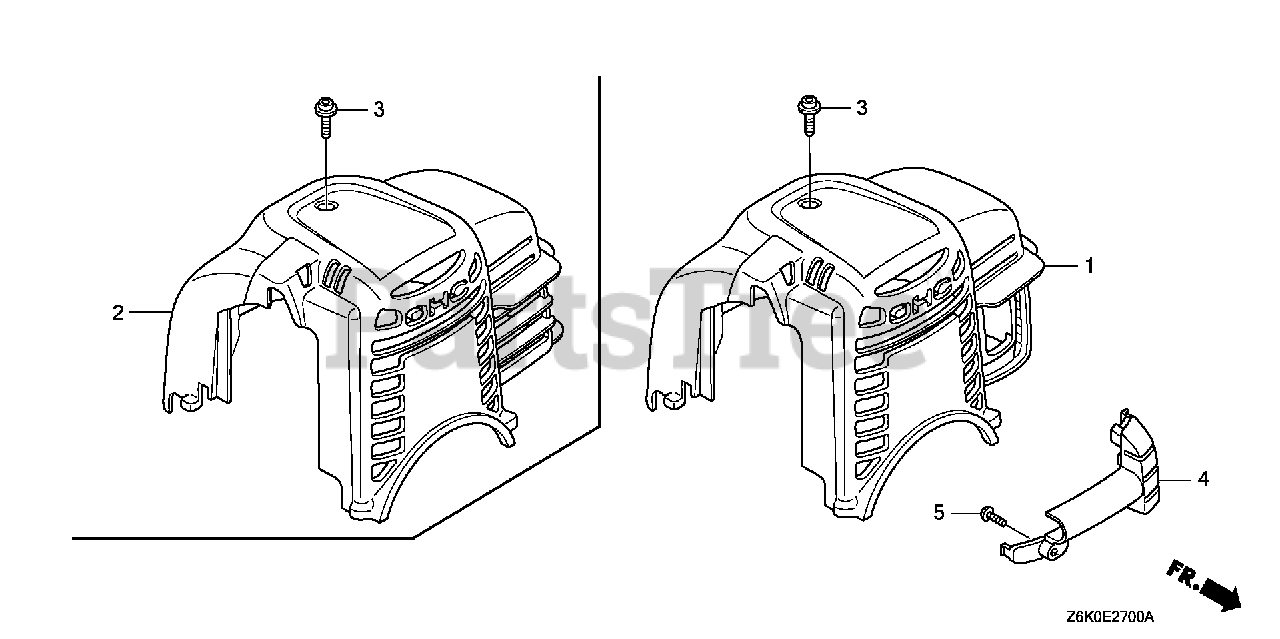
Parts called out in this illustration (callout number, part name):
2	COVER, TOP *R280* (POWER RED)
3	BOLT, TOP COVER
4	DUCT, HOT AIR
5	SCREW, TAPPING (4X10)
